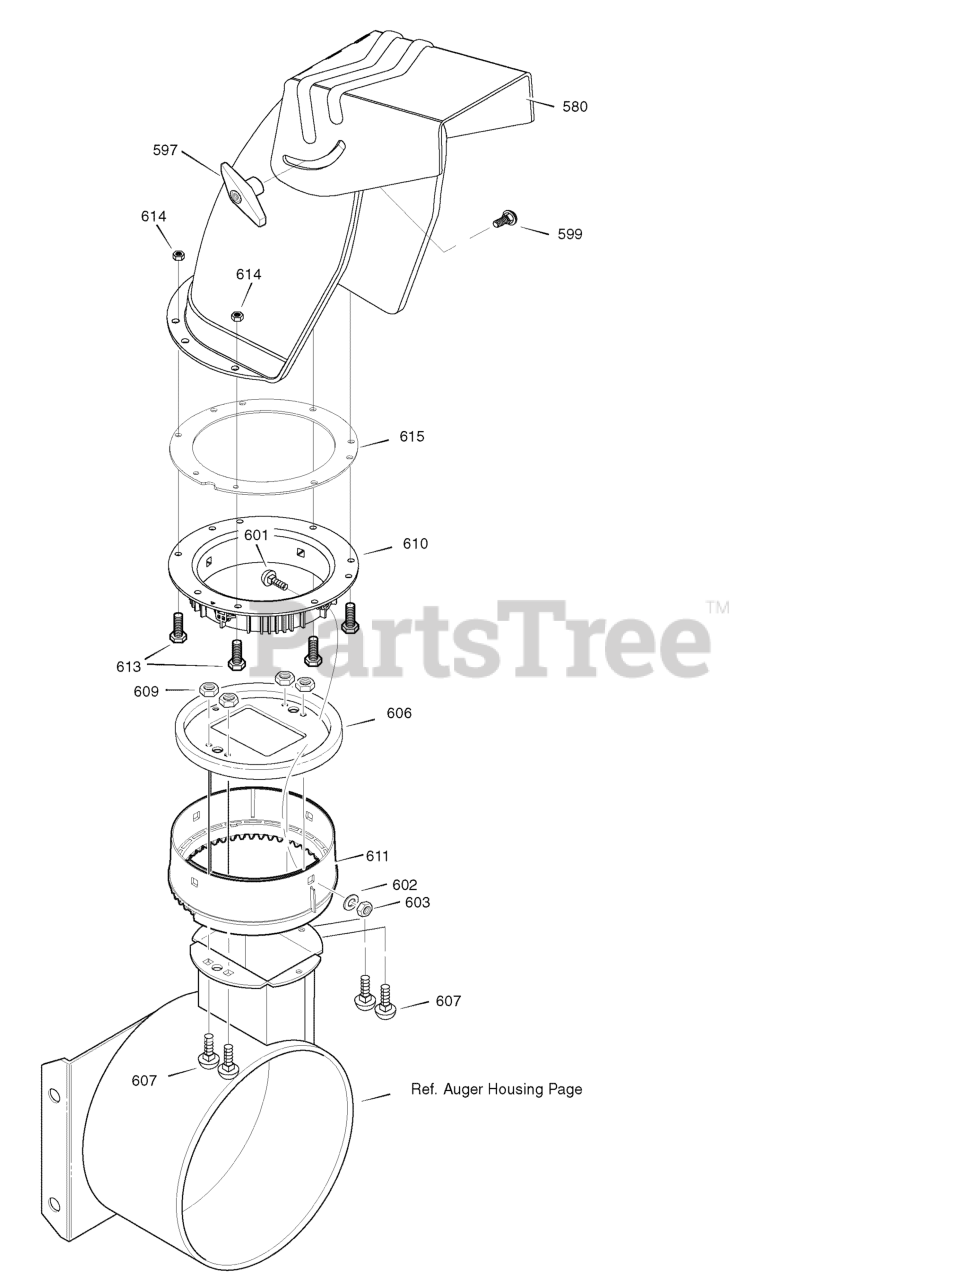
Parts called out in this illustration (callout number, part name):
580	CHUTE ASSEMBLY
597	WING KNOB
599	BOLT, 5/16-18 X 1.00
601	BOLT, 5/16-18 x 1
602	WASHER, Flat
603	NUT, Hex, Nylock, 5/16-18
606	CHUTE COLLAR
607	SCREW, 1/4-20 x 3/4
609	NUT, 1/4-20 Hex Nylock
610	RING, Retainer, Inner
611	RING, Retainer, Outer
613	CAPSCREW, Hex-Flange, 1/4-20 x 3/4
614	NUT, Nylock Flanged, 1/4-20
615	RING, Chute Base
